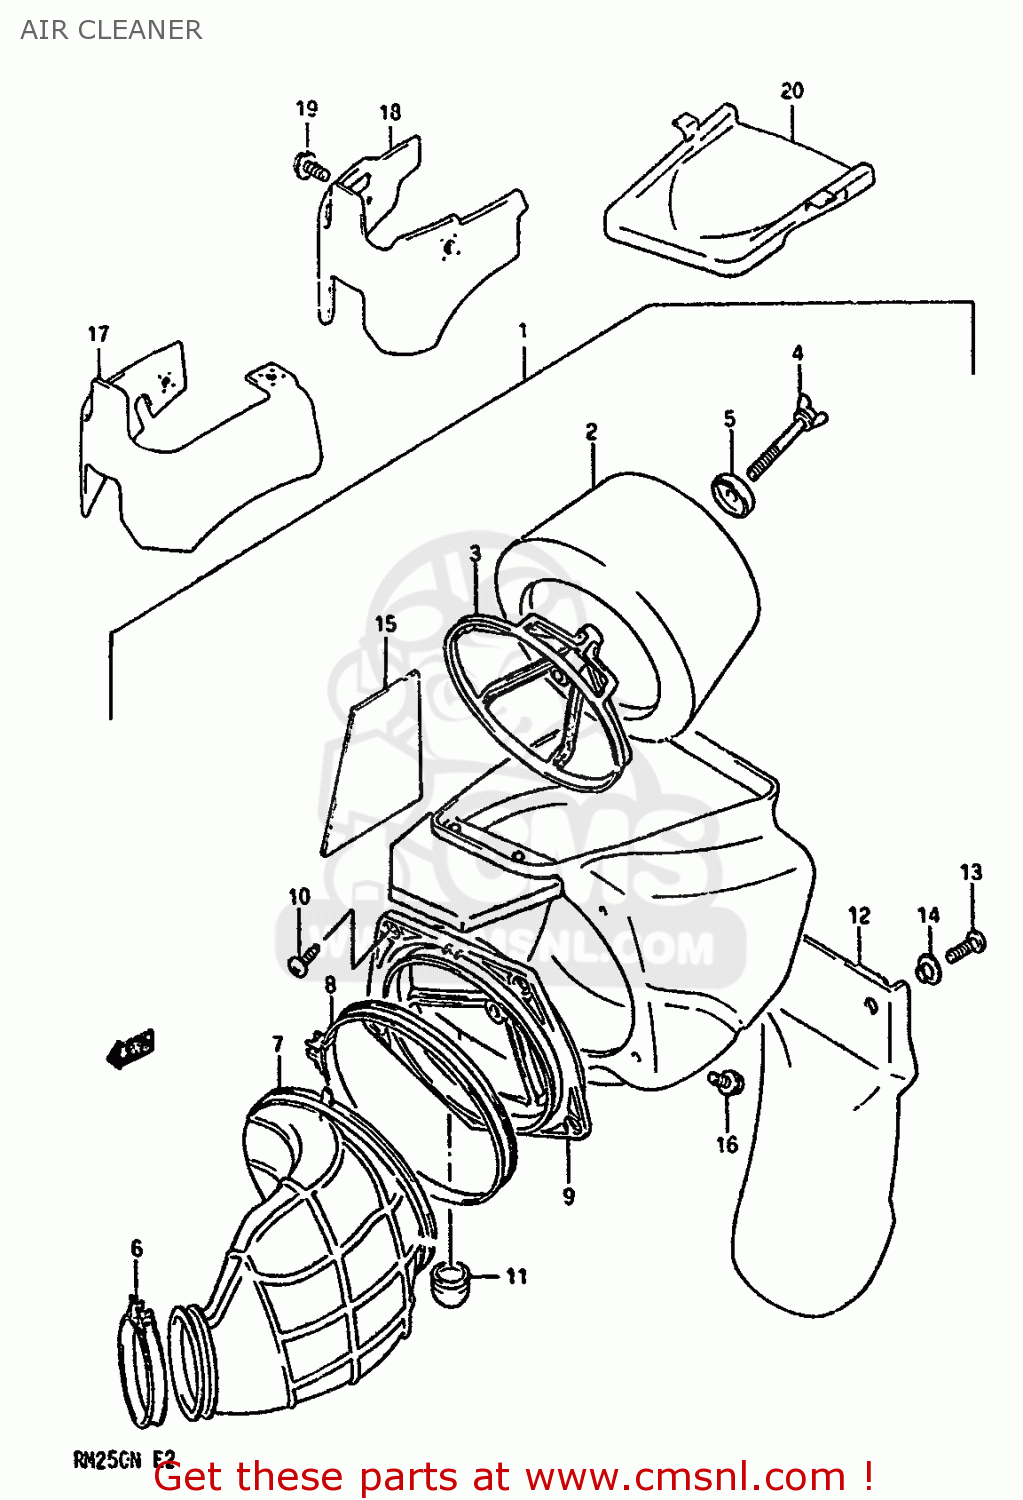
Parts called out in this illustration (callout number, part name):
1	CLEANER ASSEMBLY,AIR
2	FILTER
3	HOLDER,FILTER
4	BOLT,WING
5	WASHER,AIR CLEANER
6	CLAMP
7	TUBE,OUTLET
8	CLAMP
9	HOLDER,FILTER
10	SCREW
11	TUBE,DRAIN
12	GUARD,MUD
13	SCREW
14	COLLAR
15	TRAP,HEAT
16	BOLT 6X20
17	GUARD,MUD,C
18	GUARD,MUD
19	SCREW(6X12)
20	CAP,AIR CLEANER
